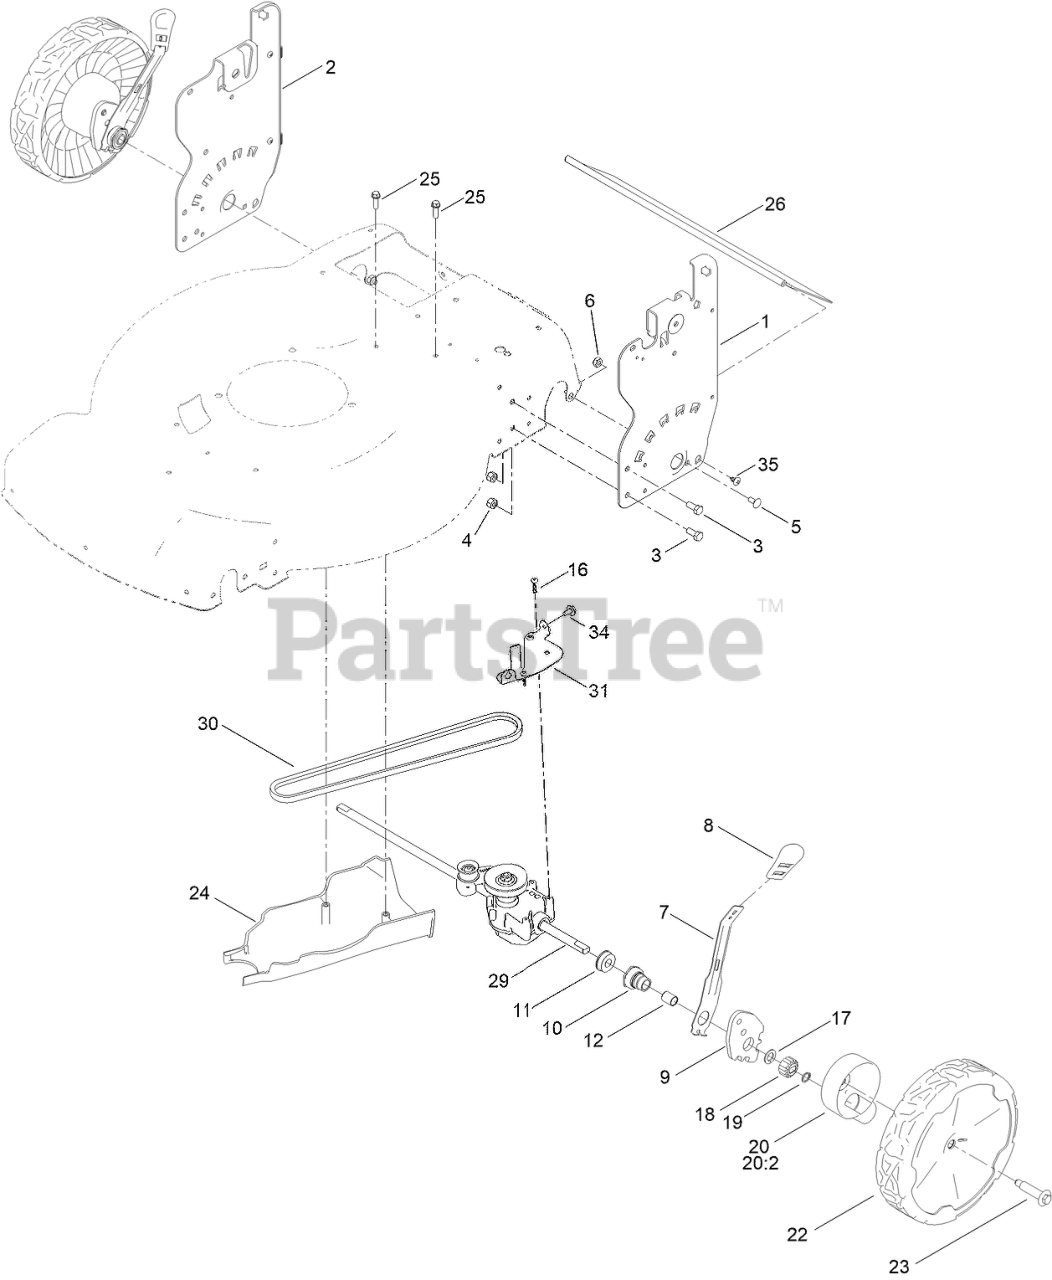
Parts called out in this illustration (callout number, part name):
1	PLATE-HOC, LH
2	PLATE-HOC, RH (ISO)
3	SCREW-HH
4	NUT-LOCK, NI
5	SCREW-CARR
6	NUT-LOCK, NI
7	ARM-SPRING
8	KNOB-HOC
9	ARM-PIVOT, REAR
10	RETAINER-BUSHING, HOC
11	BEARING-BALL
12	BUSHING-SLEEVE
16	SCREW-PLASTITE
17	WASHER-THRUST
18	GEAR-PINION, 15T
19	RING-RETAINING
20	ASM-COVER, GEAR (DK GRAY)
20:2	WASHER-STEPPED
22	ASM-9.65" WHEEL, GEARED
23	WHEEL BOLT
24	COVER-BELT, REAR
25	SCREW-HWH
26	SHIELD-TRAILING
29	TRANSMISSION-AWD
30	BELT-AWD, 34.50
31	GUIDE-BELT, AWD
34	SCREW-HHFTF
35	SCREW-PTH
